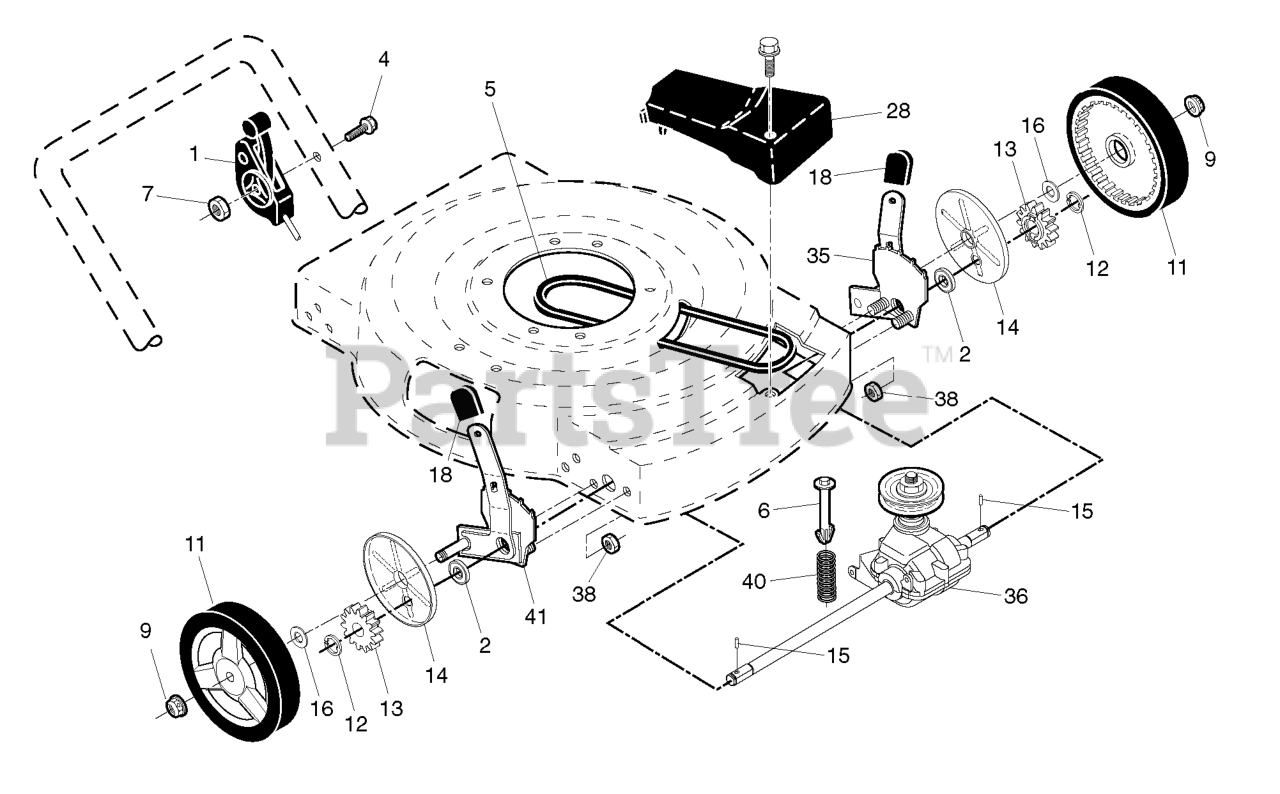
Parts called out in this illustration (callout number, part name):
1	DRIVE CONTROL 59.8 FWGD
2	BEARING
4	SCREW.PAN.HEAD
5	BELT THERM .32
6	SPRING RETAINER
7	NUT.HEX.FLANGE.1/4
9	NUT.HEX.FLANGE.3/8-16.LO(3 2)
11	WHEEL.8X1.75.H3SPK.RAD3.GY.BU3
12	E-RING 7/16 RE
13	PINION.14.TEETH.FGD
14	COVER.DUST.WHEEL
15	PAWL, DRIVE
16	WASHER FLUT
18	SELECTOR KNOB
35	KIT ADJUSTER ASM.438151.
36	TRANSMISSION.22.FGD/W/PULLEY
38	LOCKNUT.NYLOC.1/4-20
40	SPRING.EXTENSION
41	KIT ADJUSTER ASM.438148
